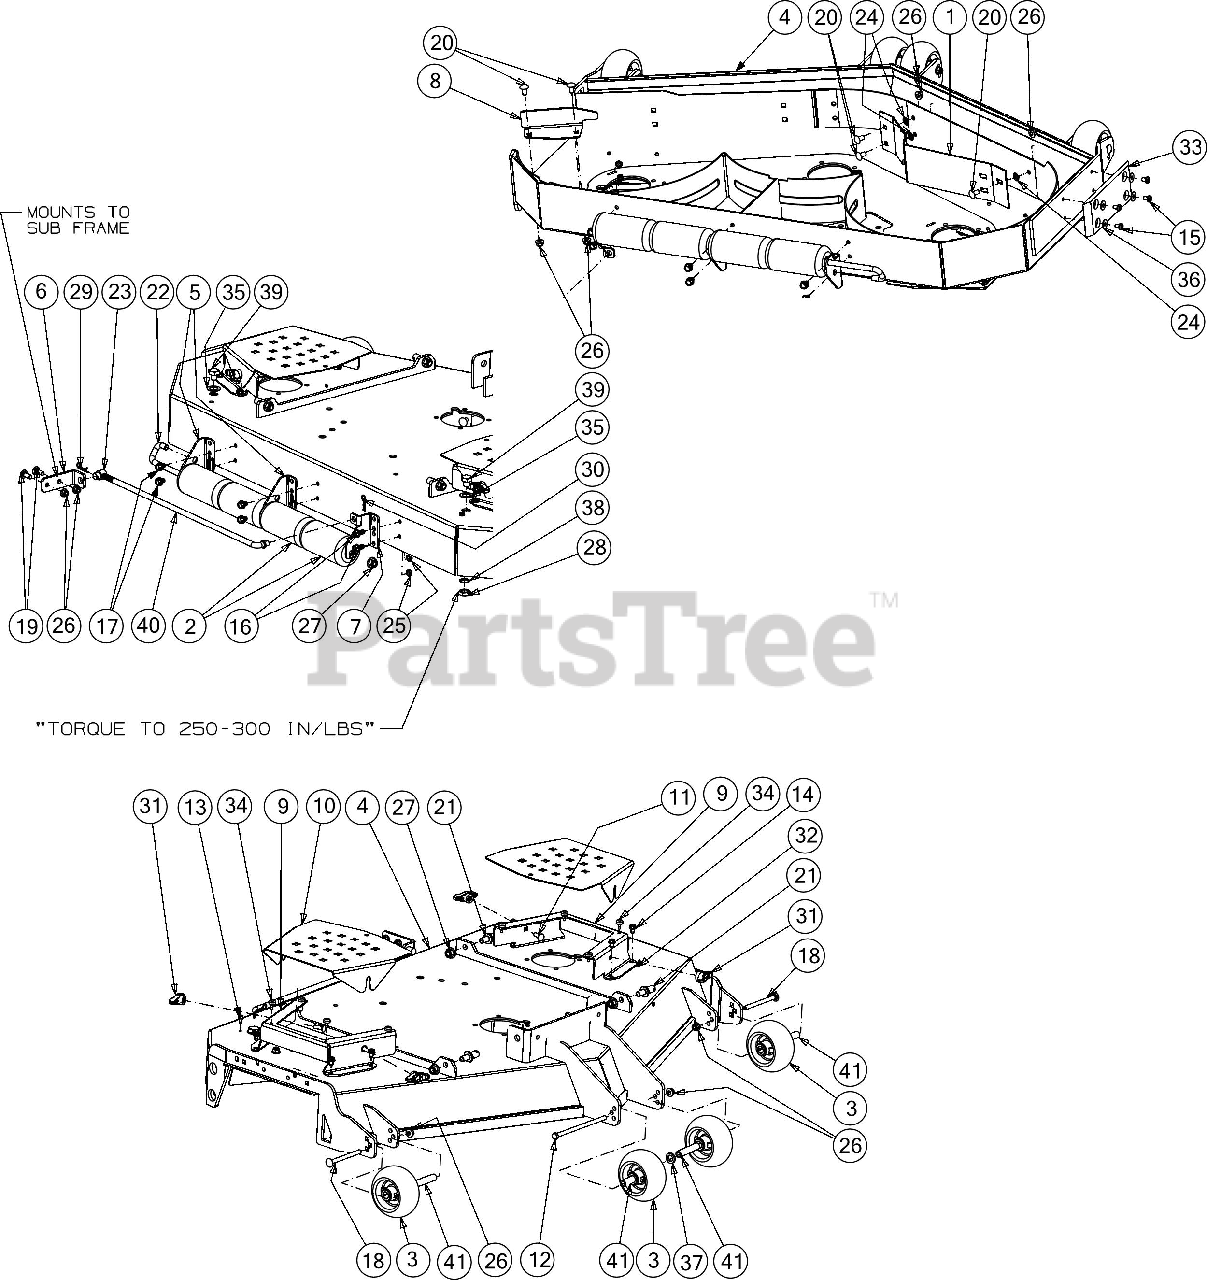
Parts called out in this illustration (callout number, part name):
1	BAFFLE - 54
2	ROLLER ASSEMBLY
3	WHEEL ASSEMBLY 5"
4	54" DECK ASSEMBLY
5	REAR MOUNT BRACKET
6	DECK MOUNT BRACKET
7	REAR ROLLER BRACKET (RH)
8	DECK CHUTE BAFFLE
9	DECK BELT COVER BRACKET
10	DECK BELT COVER
11	CARRIAGE BOLT 5/16-18 x 1.00
12	SCREW 3/8-16 x 7.25 GR5
13	SCREW 1/4-20 X.500
14	SCREW 5/16-18 x .500
15	SCREW 5/16-18.0 x 5
16	SCREW 3/8-16 x 3/4
17	SCREW 3/8-16 x .500
18	CARRIAGE BOLT 3/8-16 x 4.25 GR5
19	CARRIAGE BOLT 3/8-16 x 1.00 GR5
20	CARRIAGE BOLT 3/8-16 x .75
22	ROLLER PIN
25	JAM LOCK NUT
28	HEX NUT
29	INTERNAL COTTER PIN
30	COTTER PIN
31	WING KNOB 5/16-18
33	SKID PLATE GUARD
34	BUMPER, .62 DIA x .3
35	FLAT WASHER .793ID x 1.24OD x .060
36	FLAT WASHER
37	FLAT WASHER .632X1.00X.16
38	LOCK WASHER
39	DECK WASH PLUG
40	DECK SUPPORT ROD
41	WHEEL SPACER .38ID x 3.04LG
